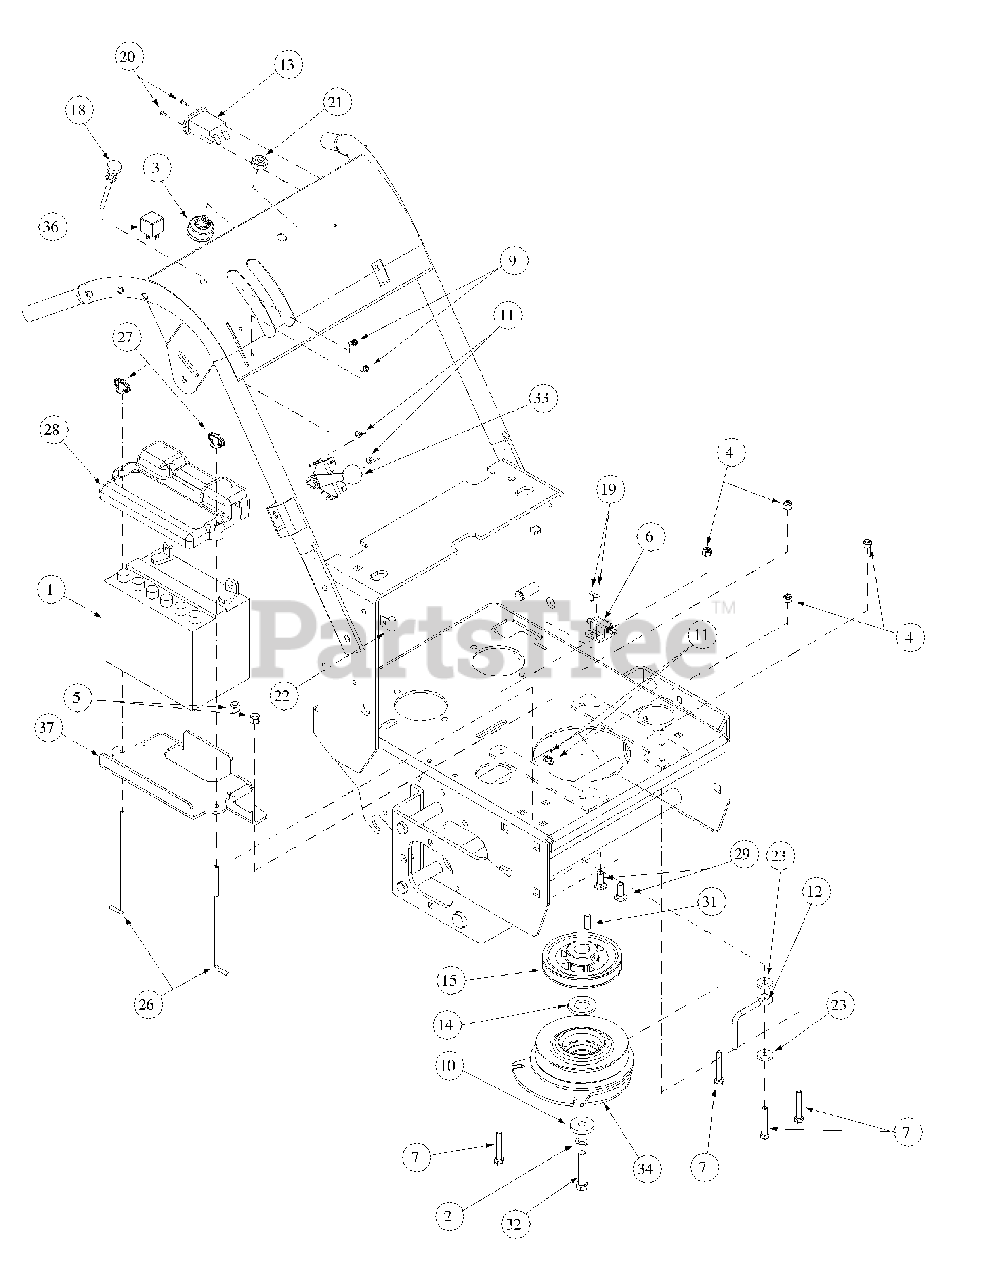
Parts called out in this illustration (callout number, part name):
1	Battery, 12V
2	Lock Washer M10
3	Ignition Switch
4	Nut, 5/16-18, Nylock
5	Lock Nut, Nylon Insert, 3/8-16
6	Switch, Delta
7	Cap Screw, 5/16-18 x 2
9	Screw, Hex Washer w/Slot, #10-3 1/2
10	Washer Clutch
11	Lock Nut, Nylon Insert, #10-32
12	Guide, Traction Drive Belt
13	Hour Meter
14	Washer, Special
15	Sheave 1" Bore w /2 Set Screws
15	Belt, Hydro Pump
15	Engine, Kohler, 20 HP Vertical
18	Cable, Choke
19	Phil. Hd. Mach. Screw, #10-32 x 5/8
20	Rivet
21	Nut, w/Cap, 5/8-32 Ignition
22	Support Clamp, 3/8 OD
23	Washer, Idler
23	Battery Cable, 15", Red
23	Battery Cable, 10" Black
26	Hold Down Rod, Battery
27	Wing Nut, 1/4-20 w/Bell Wash
28	Battery Cover Large
29	Carriage Bolt, 3/8-16 x 2
31	Key, 1/4 x 1/4 x 1
32	Capscrew, M10-1.5 x 60 mm
33	Control Throttle, w/Detent 47.25
34	Brake Clutch
34	Harness Assembly
36	Relay
37	Battery Bracket
